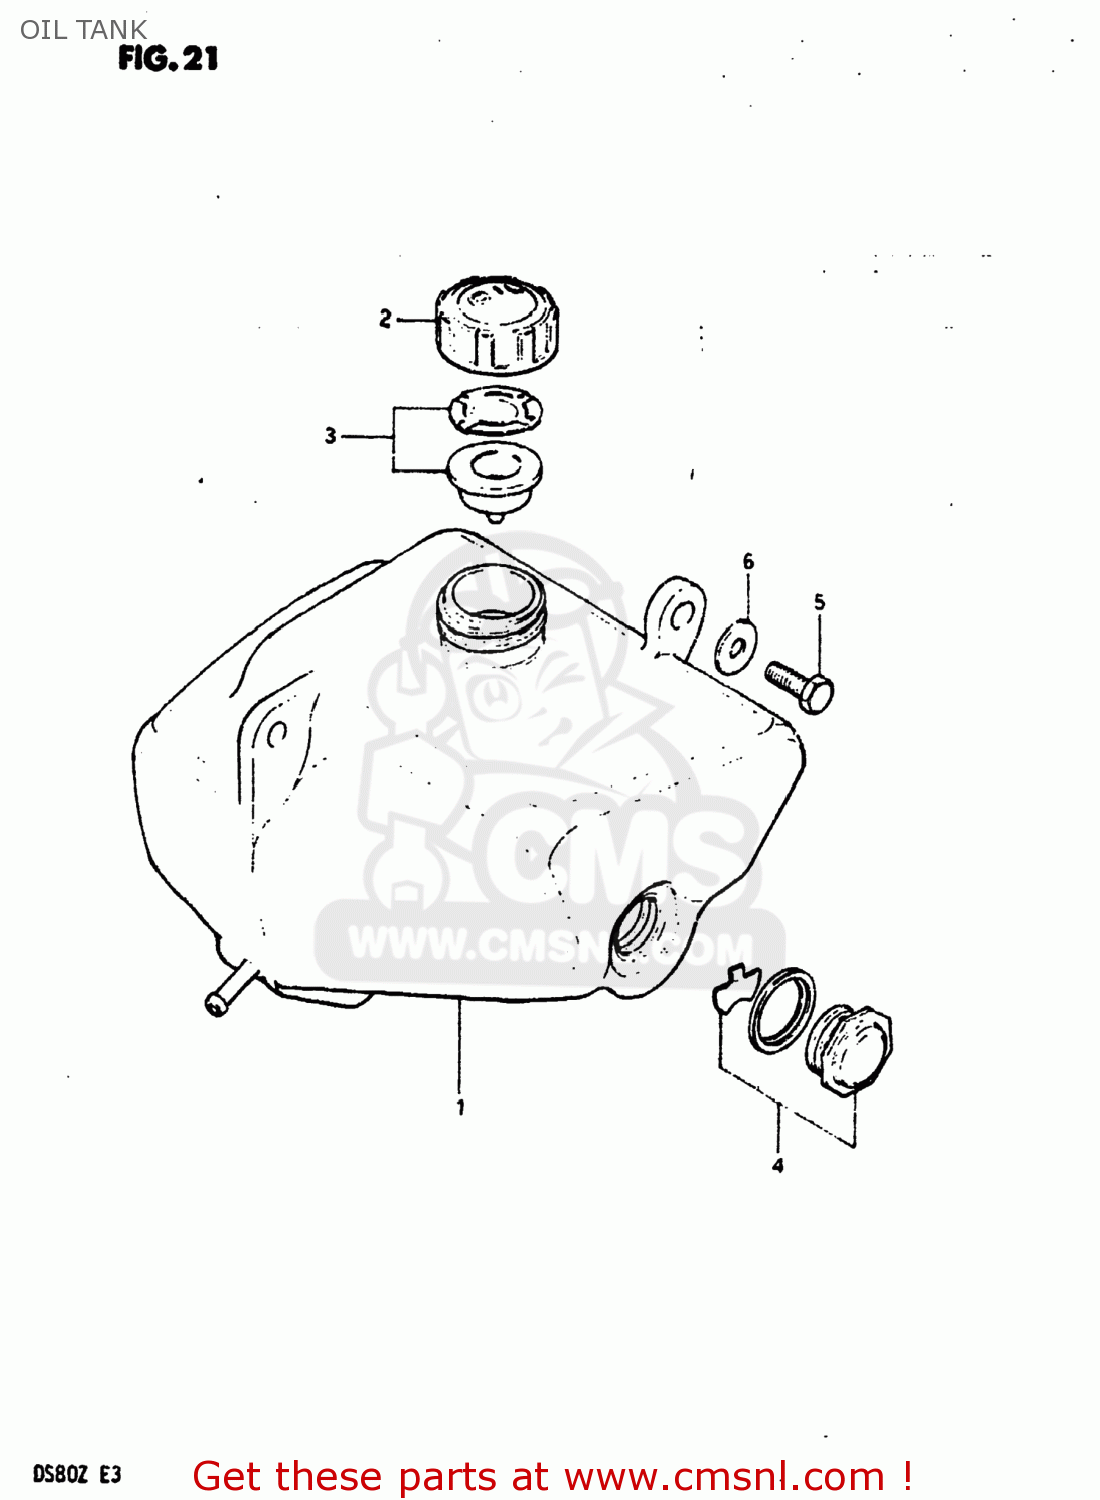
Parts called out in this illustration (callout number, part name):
1	TANK,OIL
2	CAP,OIL TANK
3	GASKET SET (NAS)
4	LENS SET,OIL LEVEL
5	BOLT, UPPER
6	WASHER
